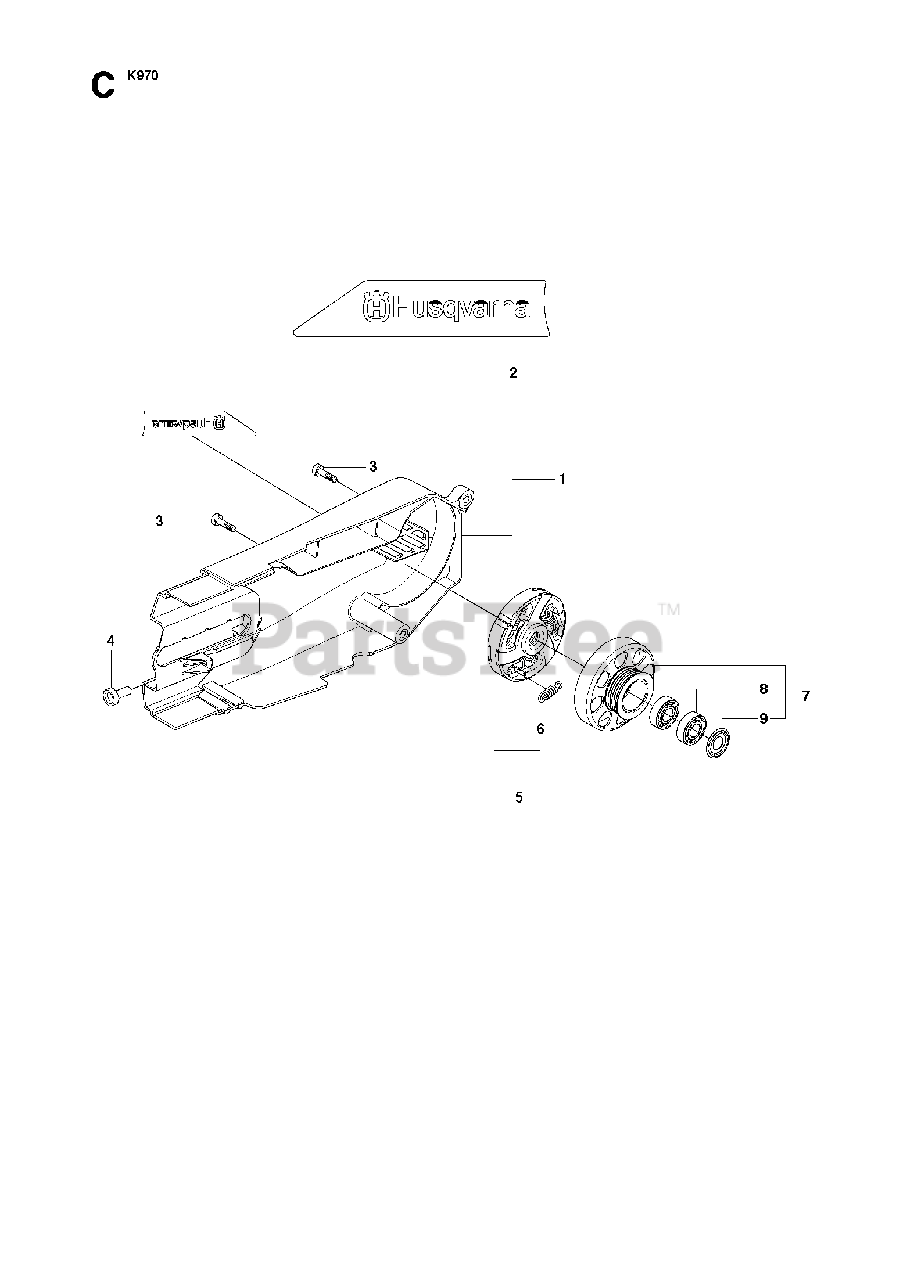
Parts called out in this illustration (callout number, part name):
1	BELT GUARD ASSY
3	SCREW ITXSCM
5	CLUTCH ASSY
6	CLUTCH SPRING
7	DRIVING PULLEY ASSY12", 14"
7	DRIVING PULLEY ASSY16"
8	BALL BEARING
